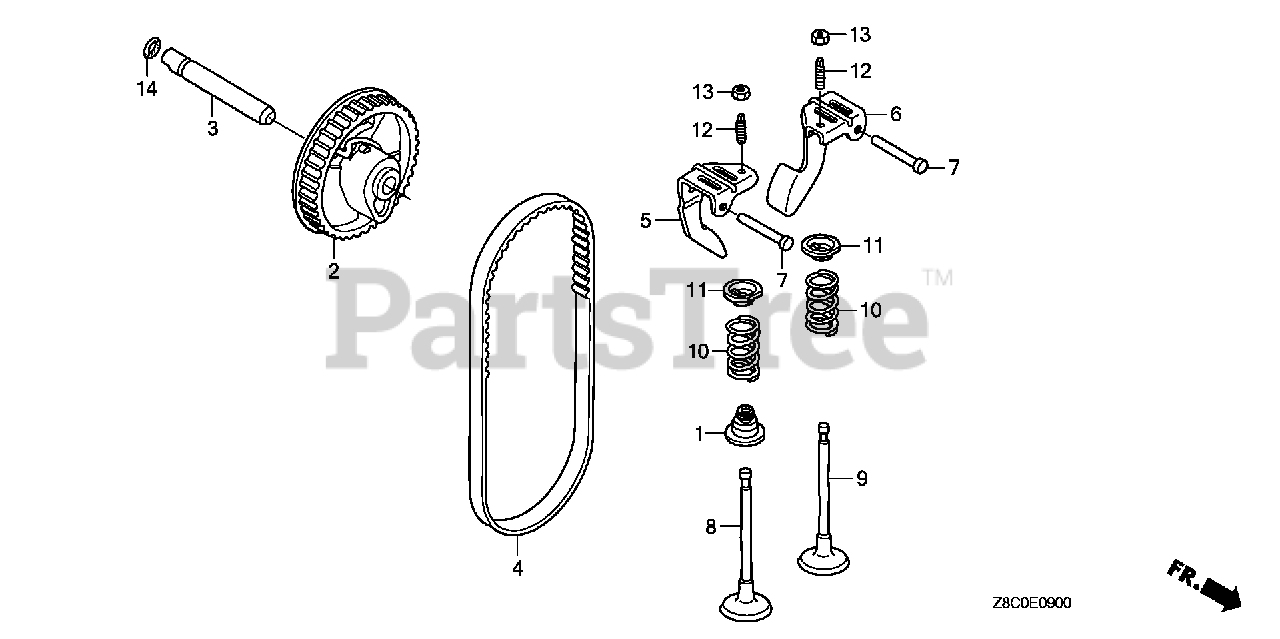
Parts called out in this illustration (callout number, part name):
1	SEAL, VALVE STEM
2	PULLEY, CAMSHAFT
3	SHAFT, CAM PULLEY
4	BELT, TIMING (84HU7 G-200)
4	BELT, TIMING (84HU6 G-200)
5	ARM, IN. VALVE ROCKER
6	ARM, EX. VALVE ROCKER
7	SHAFT, ROCKER ARM
8	VALVE, IN. (TECHNOSTAR)
9	VALVE, EX. (L8E)
9	VALVE, EX. (C8E)
10	SPRING, VALVE
11	RETAINER, VALVE SPRING
12	SCREW, TAPPET ADJUSTING
13	NUT, TAPPET ADJUSTING
14	O-RING (6.8X1.9) (ARAI)
